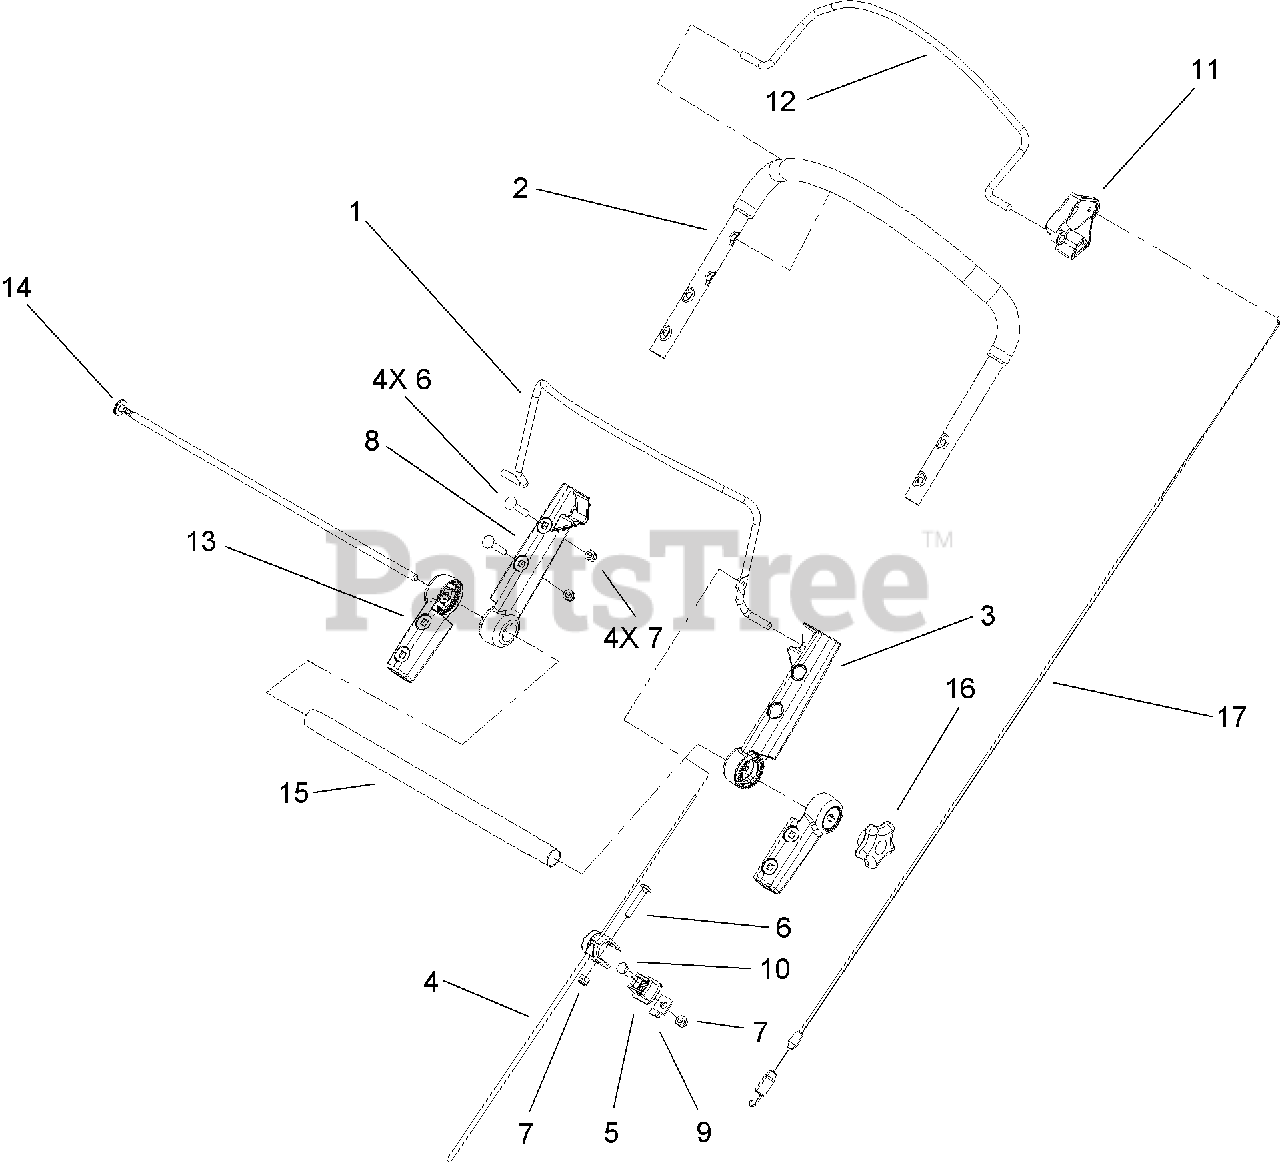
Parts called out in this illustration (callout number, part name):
2	HANDLE ASM
3	MOUNT-HANDLE, LH
4	CABLE-BRAKE
5	SUPPORT-MOUNT, CABLE
6	SCREW-CARR
7	NUT-LOCK, NI
8	MOUNT-HANDLE, RH
9	CLAMP-CABLE
10	SCREW-HH
11	STOP-BAIL
12	BAIL-TRACTION
13	MOUNT-HANDLE, LOWER
14	ROD-THREADED
17	CABLE-TRACTION
